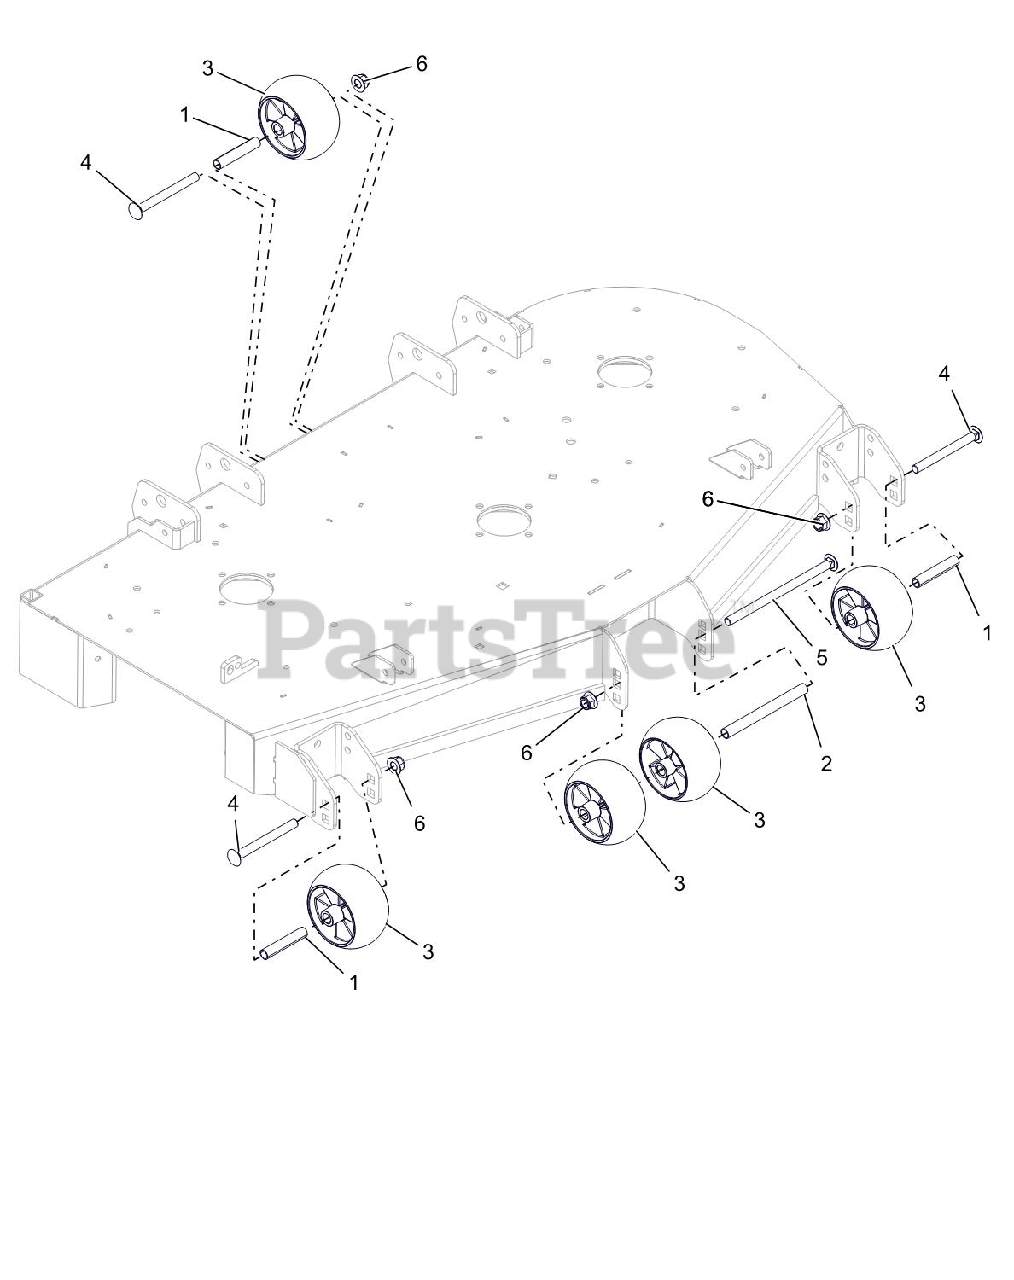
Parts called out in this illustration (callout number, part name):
1	.510X.625X3.35 SPACER-LOW FILM
2	.510X.625X6.50 SPACER-LOW FILM
3	ANTI-SCALP WHEEL - 5X3 CTR
4	BLT-RDHDSQNK .50-13X5.00 GR5YZ
5	@BLT-RDHDSQNK .50-13X8.50 G5YZ
6	@NUT-LK-NYL-FLG .50-13 YWZC
